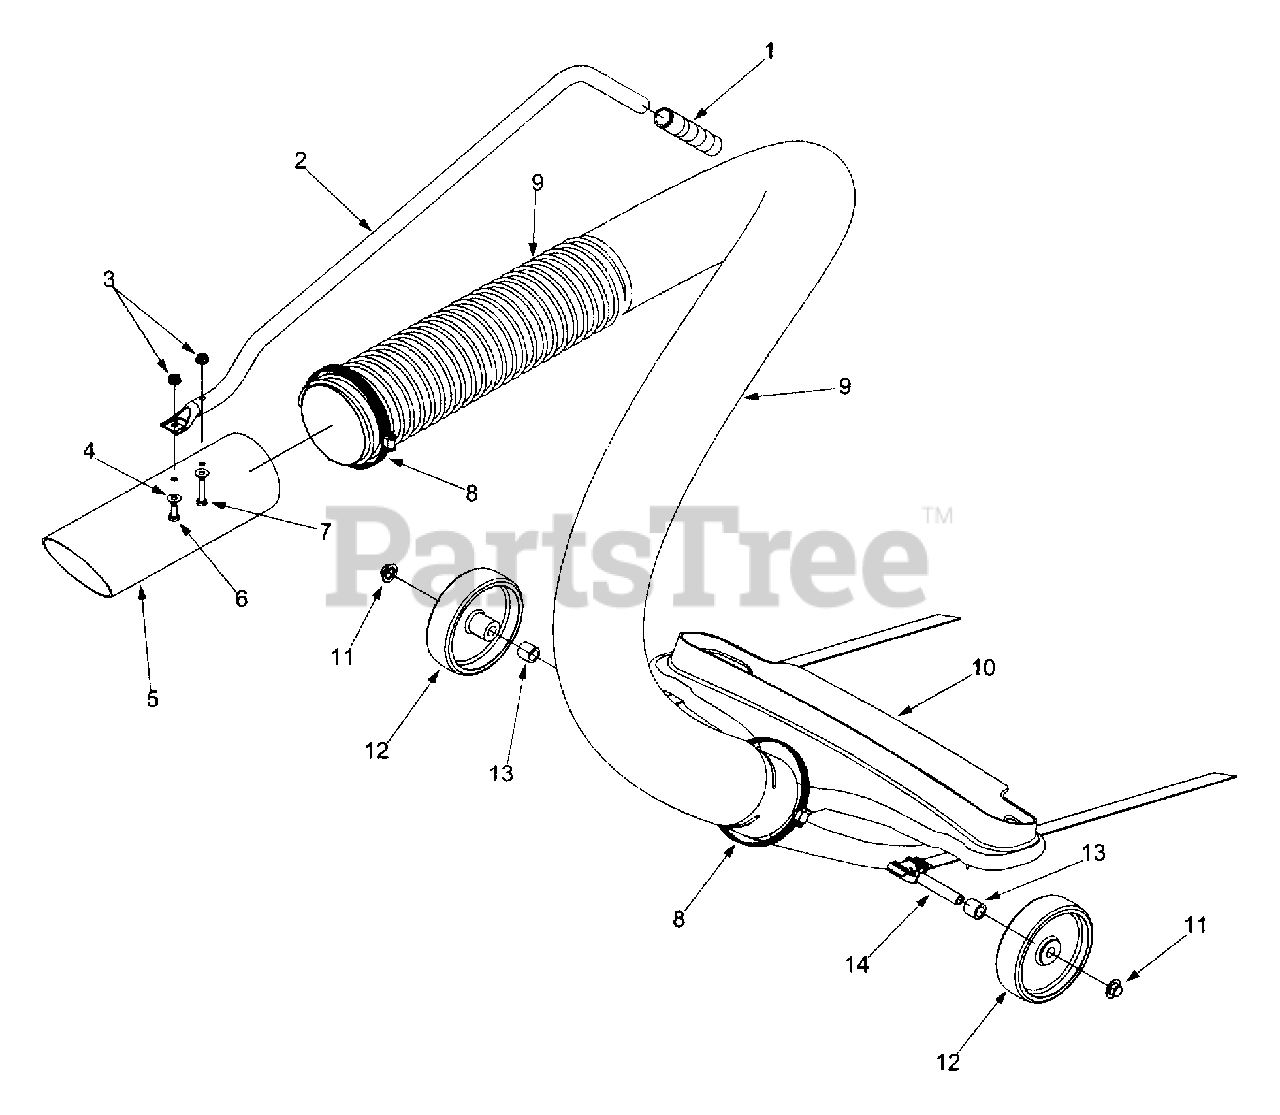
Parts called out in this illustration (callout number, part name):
1	Handle Grip
3	Hex Lock Nut 1/4-20
4	Flat Washer .271 ID x .630 OD
5	Nozzle 3.875 x 12.0
6	Hex Cap Screw 1/4-20 x .620
7	Hex Cap Screw 1/4-20 x 1.25
8	Adjustable Clamp
9	Vacuum Hose
10	Hose Attachment Nozzle Ass'y
11	Push Cap
12	Wheel 5.0 x 1.38
13	Spacer
14	Axle .50 OD x .354 ID x 16.7
